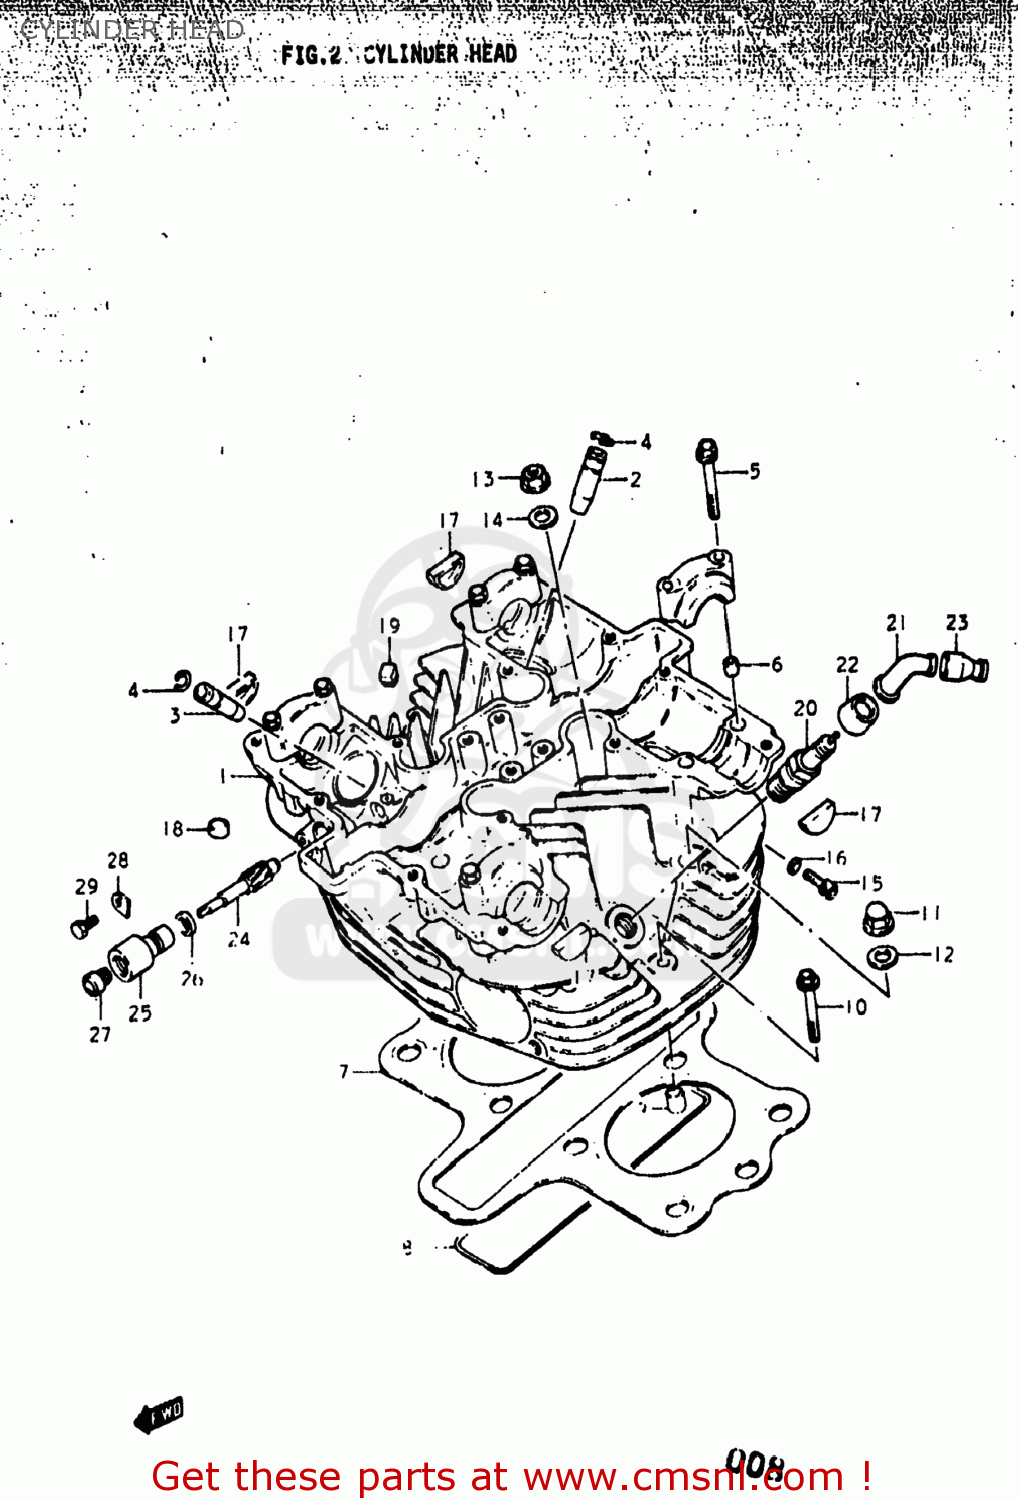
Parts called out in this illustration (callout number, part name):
1	HEAD ASSEMBLY,CYLINDER
2	GUIDE,VALVE
3	GUIDE,VALVE
4	CIRCLIP
5	BOLT(6X39)
6	PIN(6.2X8X11)
7	GASKET,CYLINDER HEAD (MCA)
8	O RING(D:3,ID:26X157)
9	PIN
10	BOLT
11	NUT
12	GASKET(10.5X22X2) (NAS)
13	NUT
14	WASHER(10.5X22X2.3)
15	BOLT
16	GASKET(5.3X9.3X1.2) (NAS)
17	PLUG
18	PAD,CYLINDER HEAD
19	PAD
20	PLUG,SPARK
21	CAP,SPARK PLUG
22	SEAL,SPARK PLUG
23	SEAL,SPARK PLU
24	GEAR,TACHOMETER DRIVEN
25	SLEEVE,TACHOMETER DRIVE
26	SEAL,TACHOMETER DRIVEN
27	SEAL
28	PLATE,TACH DRIVE GEAR SLEEVE
29	SCREW(5X12)
